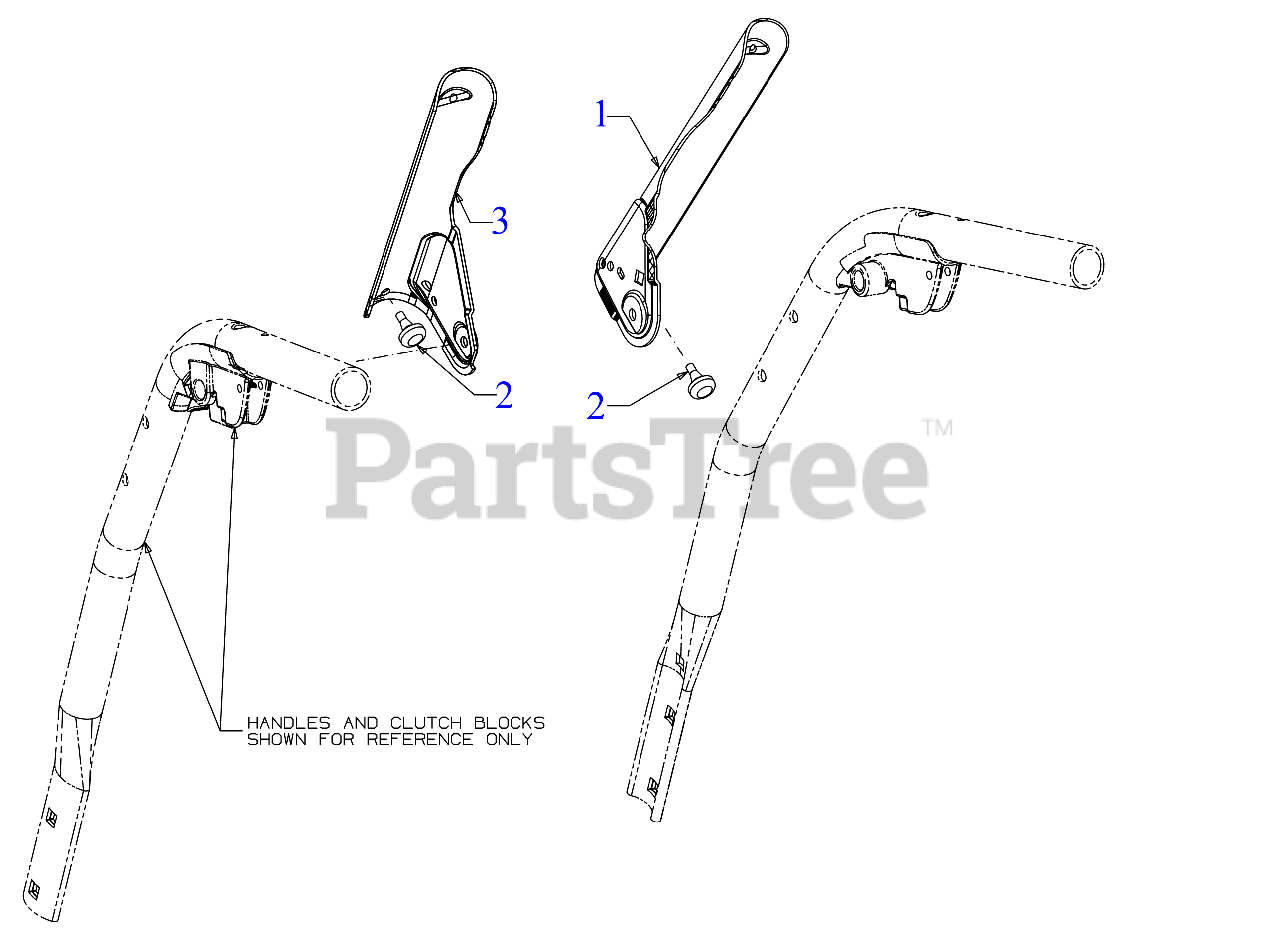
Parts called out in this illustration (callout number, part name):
1	ENGAGEMENT HANDLE (RH) (POWDER BLACK)
2	RUBBER BUMPER
3	ENGAGEMENT HANDLE (LH) (POWDER BLACK)
